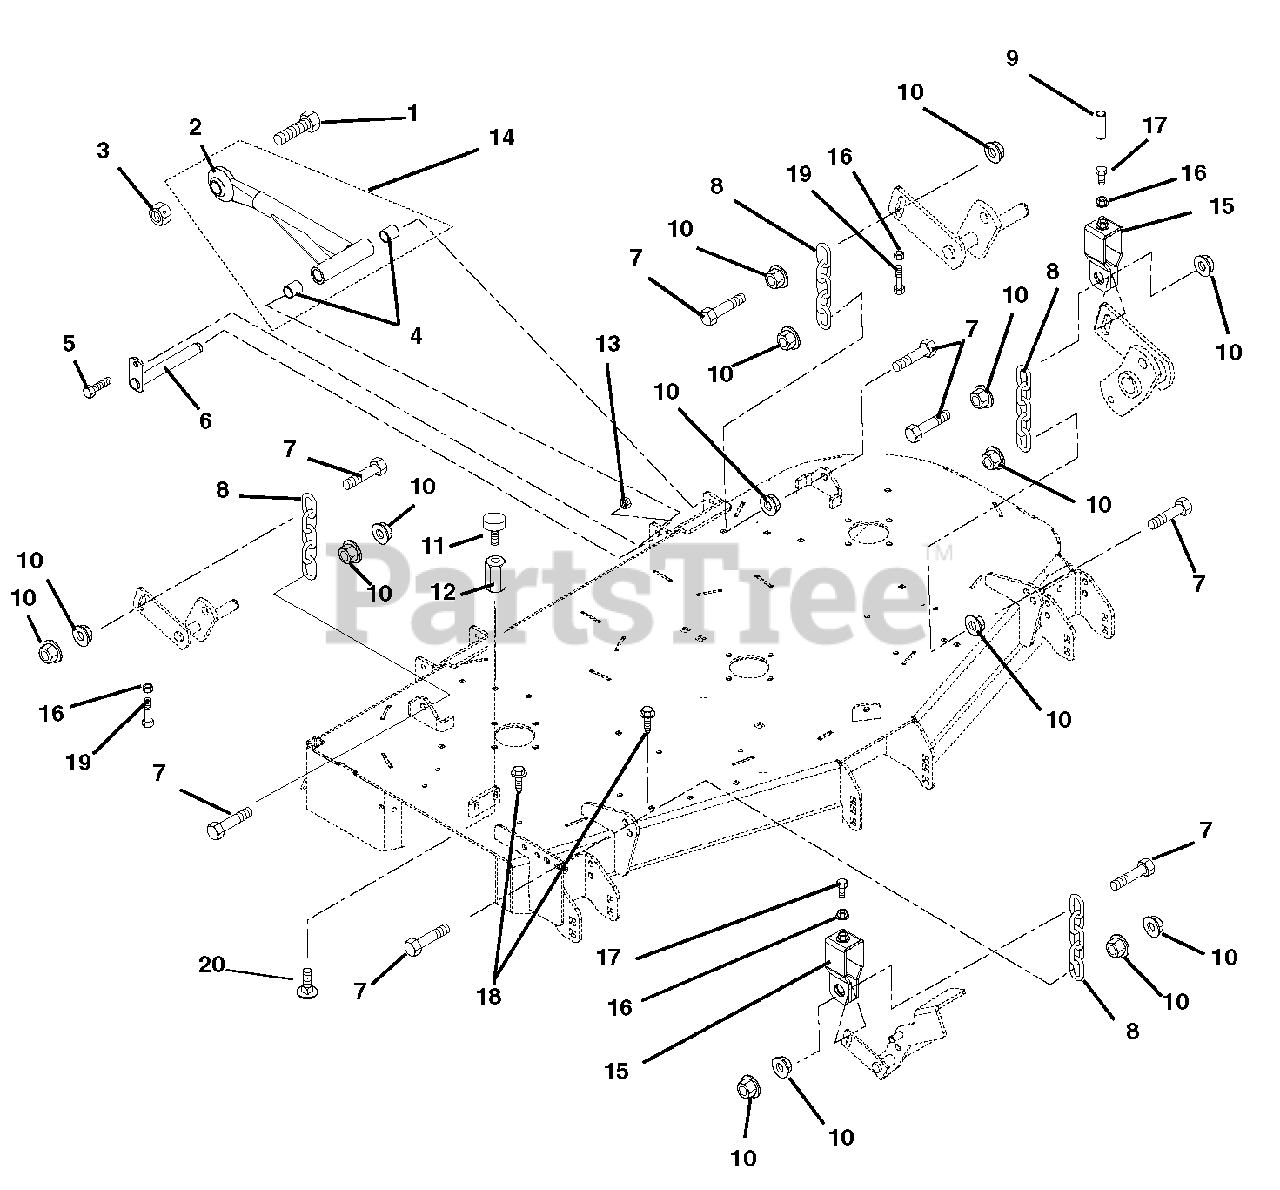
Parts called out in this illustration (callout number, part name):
1	Bolt, Hex .875-9 x 2.75 Grade 5
2	Mower Mounting Arm Weldment
3	Nut, Locking Center .875-9
4	Bearing, .75 x .875 x 1.00
5	Bolt, Hex .38-16 x 1.00 Grade 5
6	Weldment, Mower Mounting Pin
7	Bolt, Hex M12-1.75 x 50 Grade 5
8	Chain, Link
9	Cap, Vinyl .50ID x 1.50LG x .055
10	Nut, Spin Lock Flange M12-1.75
11	Bumper, Rubber
12	Coupling Nut, .31-18 x 3.00
13	Nut, .38-16 Nyloc Flange
14	Assembly, Mower Mounting Arm (Includes item # 2 and item # 4)
15	Bracket, Deck Leveling
16	Nut, Jam .312-18
17	Bolt, Hex .31-18 x 2.00 Full Thread
18	Screw, Tapping .38-16 x .50 Hex Washer Head Thread (195)
19	Bolt, Hex .312-18 x 1.50 Grade 5
20	Bolt, Round Head Square Neck .31-18 x .75 Loc-Tite
